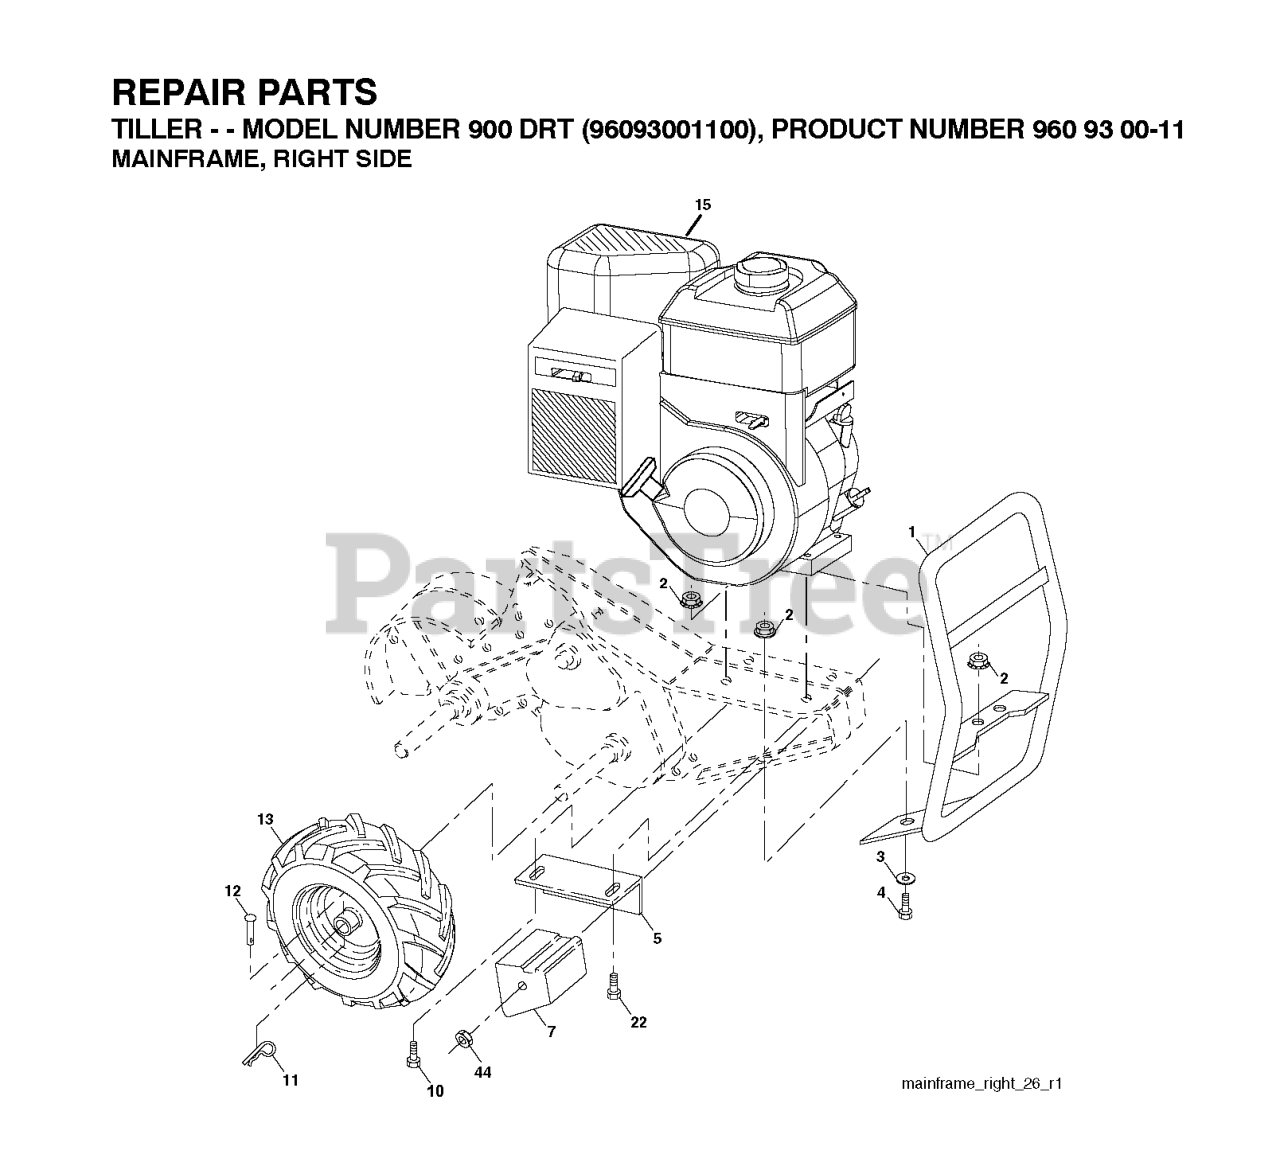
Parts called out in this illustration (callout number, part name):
1	RP.BUMPER.ASM.TILLER.
2	LOCKNUT-FLANGE 5/16-18
3	WASHER
4	BOLT
5	DNO BRACKET RH CRT
6	BOLT, HEX 5/16-18X1-3/4
7	COUNTERWEIGHT, RH
10	BOLT
11	RETAINER M
12	RIVET,DRILLED
13	RIM.ASM.6".SILVER
13	TIRE.13X5-6.CHEVRON.TILLER
13	VALVE STEM LT
